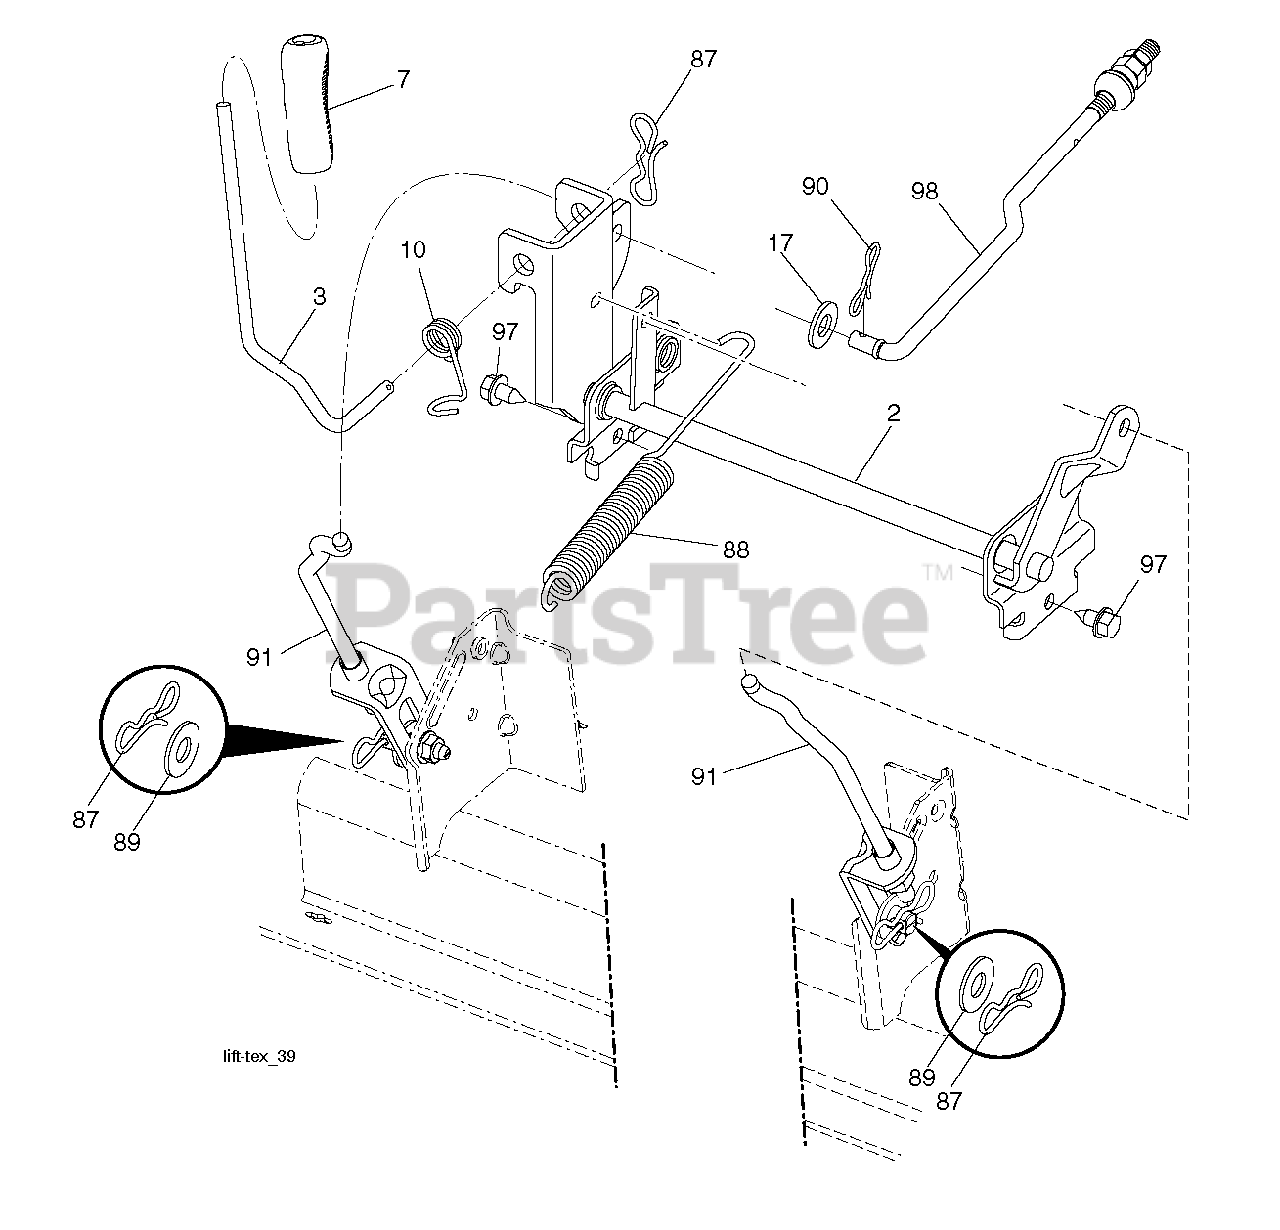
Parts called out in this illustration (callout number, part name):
2	SHAFT.ASM.CROSS.LIFT
3	LEVER.LIFT.HANDLE.LT
7	GRIP.HANDLE.LIFT.PVC.BLACK
10	SPRING.TORSION.LIFT.HANDLE
17	WASHER
87	PIN.COTTER.7/16.BOW TI.
88	SPRING.LIFT.ASSIST
89	WASHER.CLEAR.ZINC
90	PIN.COTTER.5/16.BOW TI
91	LINK.ASM.LIFT.REAR
97	SCREW, 3/8-16X3/4
98	LINK.ASM.SUSP.FRONT.MW
